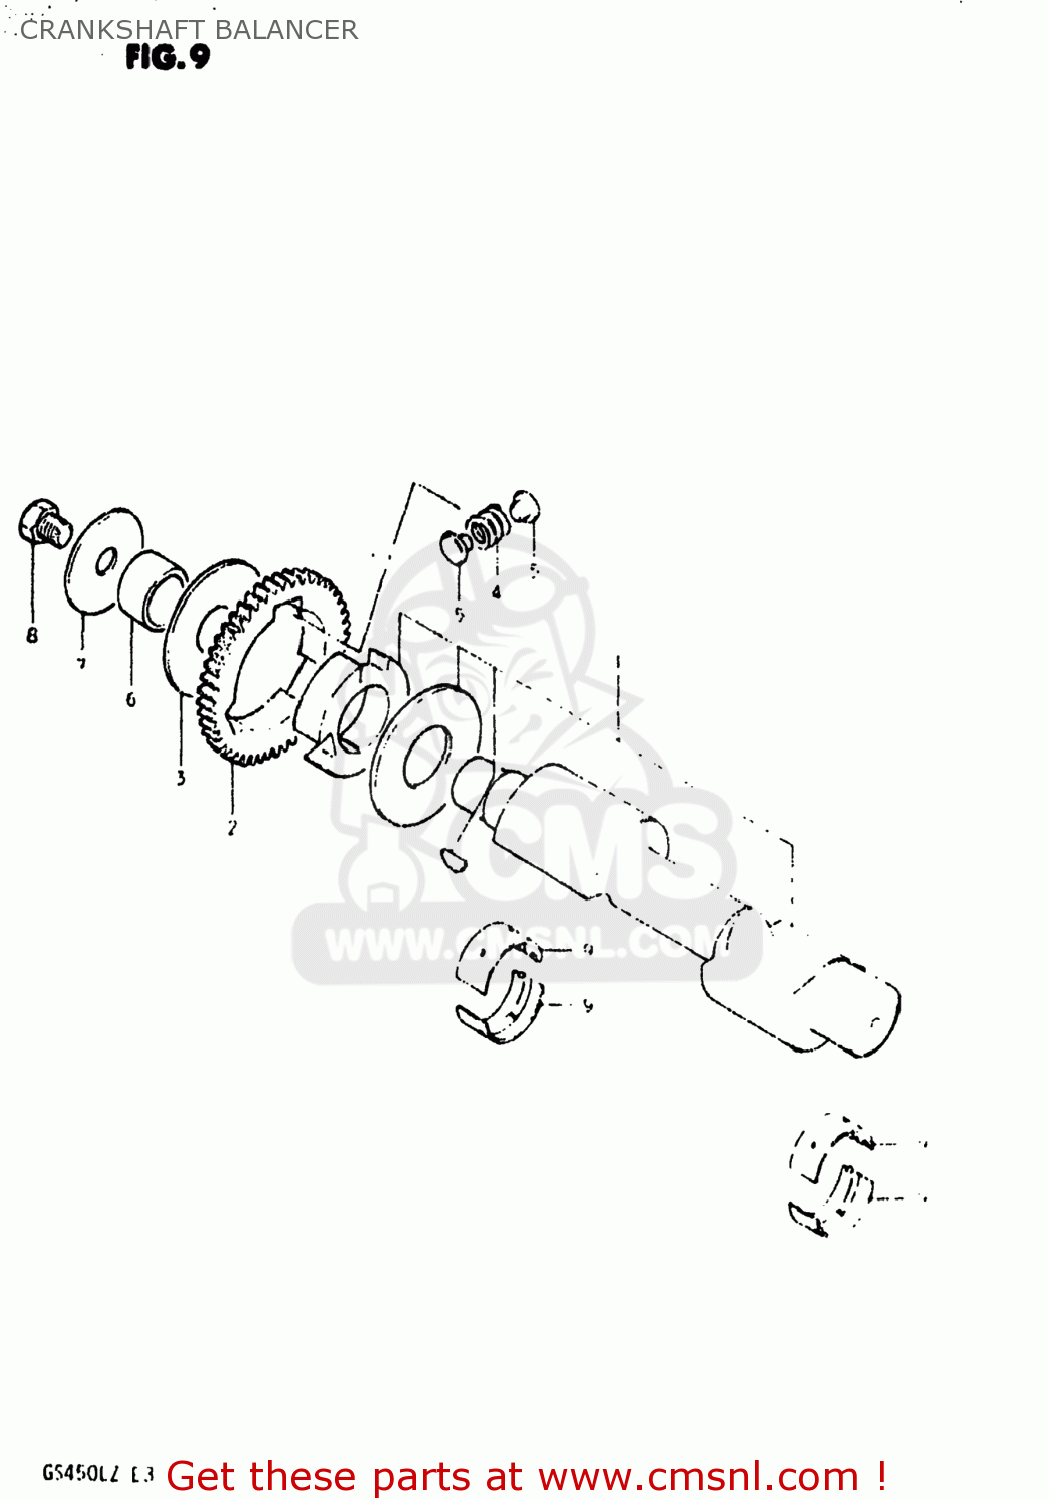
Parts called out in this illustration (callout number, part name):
1	BALANCER,CRANKSHAFT
2	GEAR,CRANK BALANCER DRIVE
3	WASHER
4	SPRING
5	PIN
6	SPACER
7	WASHER(12X50X3)
8	BOLT
9	METAL CRANKSHAFT
